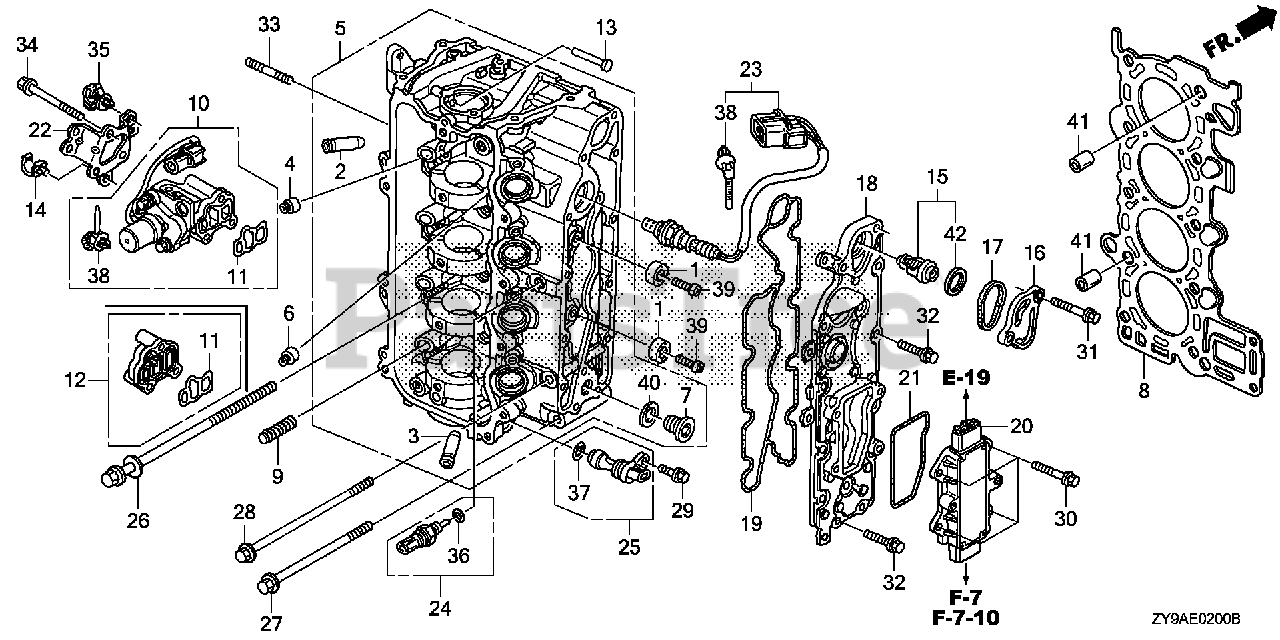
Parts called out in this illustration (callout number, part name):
1	METAL, ANODE
2	GUIDE, VALVE (OVER SIZE)
3	GUIDE, EX. VALVE (OVER SIZE)
4	SEAL A, VALVE STEM (NOK)
5	CYLINDER HEAD *NH8* (DARK GRAY)
6	SEAL B, VALVE STEM (NOK)
7	BOLT, SEALING (20MM)
8	GASKET, CYLINDER HEAD
9	MOTION, LOST
10	VALVE ASSY., SPOOL *NH8* (DARK GRAY)
11	FILTER ASSY., SPOOL VALVE
13	LIFTER, FUEL PUMP
14	CLAMP B, FUEL TUBE
15	THERMOSTAT ASSY.
16	COVER, THERMOSTAT
17	O-RING, THERMOSTAT COVER
18	COVER, WATER JACKET
19	GASKET, EX. WATER JACKET COVER
20	RECTIFIER ASSY., REGULATOR
21	GASKET, REGULATOR
22	BRACKET D, HARNESS CLIP
23	SENSOR, OXYGEN
24	SENSOR ASSY., WATER TEMPERATURE
25	SENSOR ASSY., TDC
26	BOLT-WASHER (9X155)
27	BOLT, FLANGE (8X95)
28	BOLT, FLANGE (8X110)
29	BOLT, FLANGE (6X16)
30	BOLT, FLANGE (6X20)
31	BOLT, FLANGE (6X35)
32	BOLT, FLANGE (6X22)
33	BOLT, STUD (8X32)
34	BOLT, FLANGE (6X55)
35	CLIP, HARNESS
36	O-RING (9.5X1.9)
37	O-RING (15X1.9)
38	CLIP, HARNESS BAND (145MM) (BLACK)
39	SCREW, PAN (6X18)
40	WASHER, DRAIN PLUG (20MM)
41	PIN A, DOWEL (14X20)
42	RUBBER, RING
